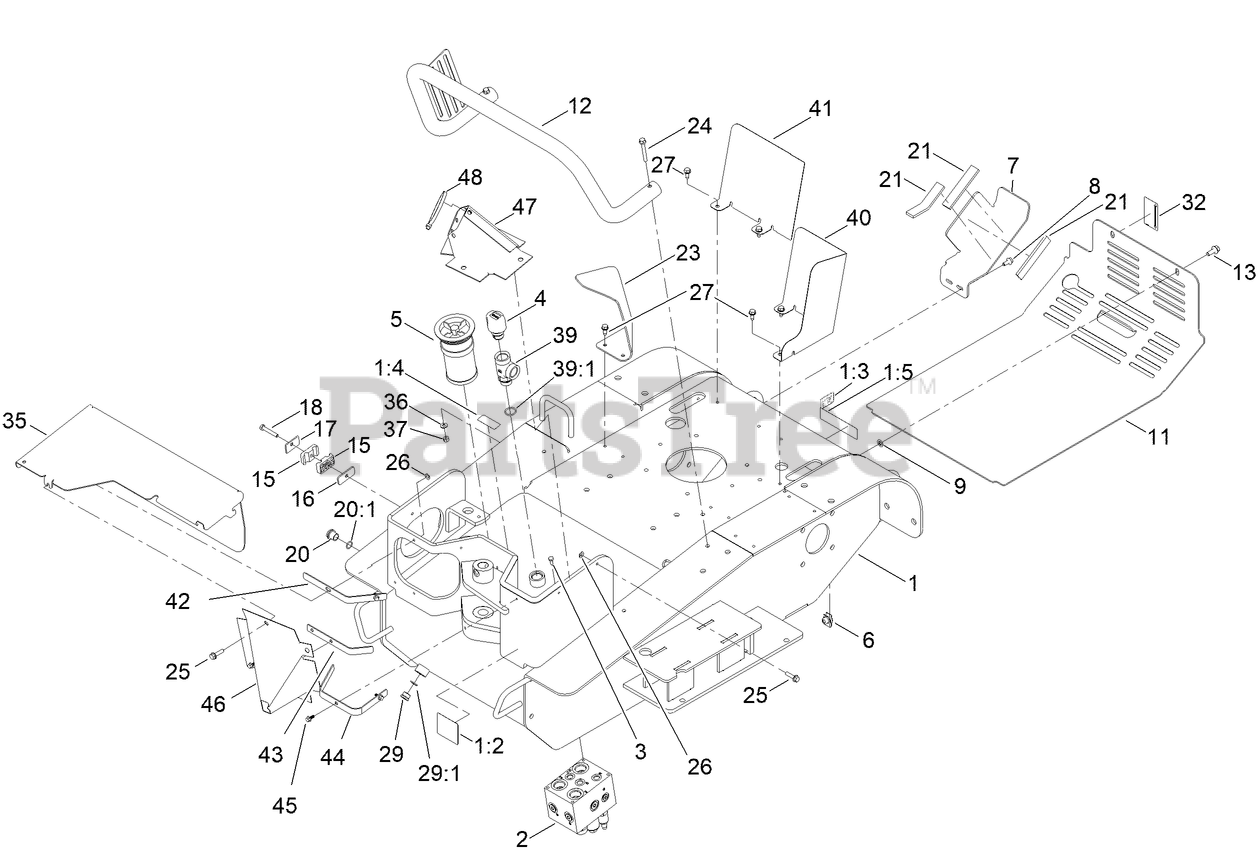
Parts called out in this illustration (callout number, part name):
1	FRAME-MAIN
1:2	DECAL-WARNING
1:3	DECAL-LIFT, TIE DOWN
1:4	DECAL-OIL, HYD
1:5	DECAL-DANGER
2	VALVE-CUTTER
3	SCREW-HH
4	BREATHER
5	CARTRIDGE-FILTER
6	NUT-TINNERMAN
7	BRACKET-TANK
8	SCREW-HHF
9	NUT-PUSH
11	COVER-REAR
12	MUFFLER GUARD DECAL ASM
13	SCREW-HHF
15	CLAMP-TUBE
16	PLATE-CLAMP
17	COVERPLATE
18	SCREW-HH
20	SIGHT GLASS ASM
20:1	O-RING
21	PAD-FOAM
23	PLATE-DEFLECTOR, RH
24	SCREW-HHF
25	SCREW-HHF
26	NUT-PUSH
27	SCREW-HWHTF
29	PLUG-HEX
29:1	O-RING
32	DECAL-BRAKE, PARKING
35	COVER, HYDRAULIC
36	WASHER-PLAIN
37	NUT-LOCK, NI
39	FITTING-TEE
39:1	O-RING
42	BRACKET-FRAME, TOP
43	BRACKET-FRAME, BOTTOM
44	BRACKET-BOOT
45	SCREW-HHF
46	COVER, CANVAS CYLINDER
47	COVER, CANVAS HYD HOSES
48	TIE-CABLE
